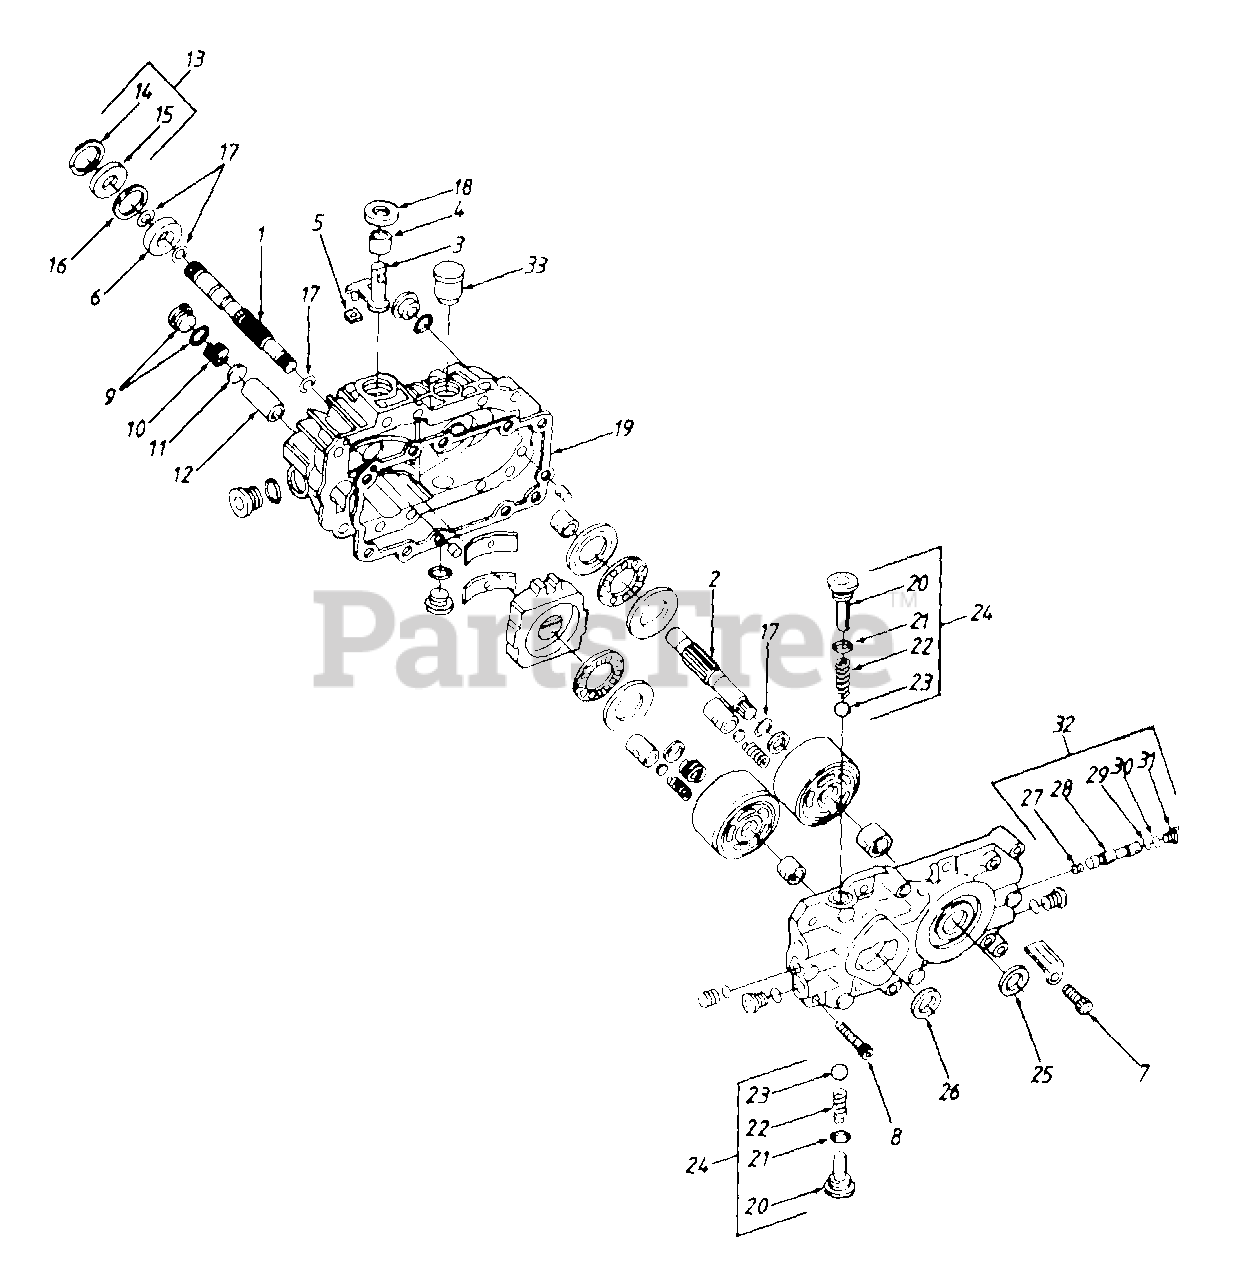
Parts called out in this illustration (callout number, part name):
1	Shaft - Pump
2	Shaft - Motor
3	Arm, Trunnion
4	Bearing, Journal
5	Guide, Slot
6	Bearing, Ball
7	Screw, Socket Head
8	Screw, Socket Head
9	Plug
10	Spring, Fllter
11	Washer, Fllter
12	Filter
13	Kit, Seal
14	Ring, Retaining
15	Seal, Lip
16	Spacer
17	Ring, Retaining
18	Seal, Lip
19	Gasket
21	O-Ring
24	Kit, Check Valve
25	Seal, Lip
26	Seal, Lip
27	Spring
28	Spool, Bypass
29	O-Ring
30	O-Ring
32	Kit, Bypass Valve
33	Reservoir
